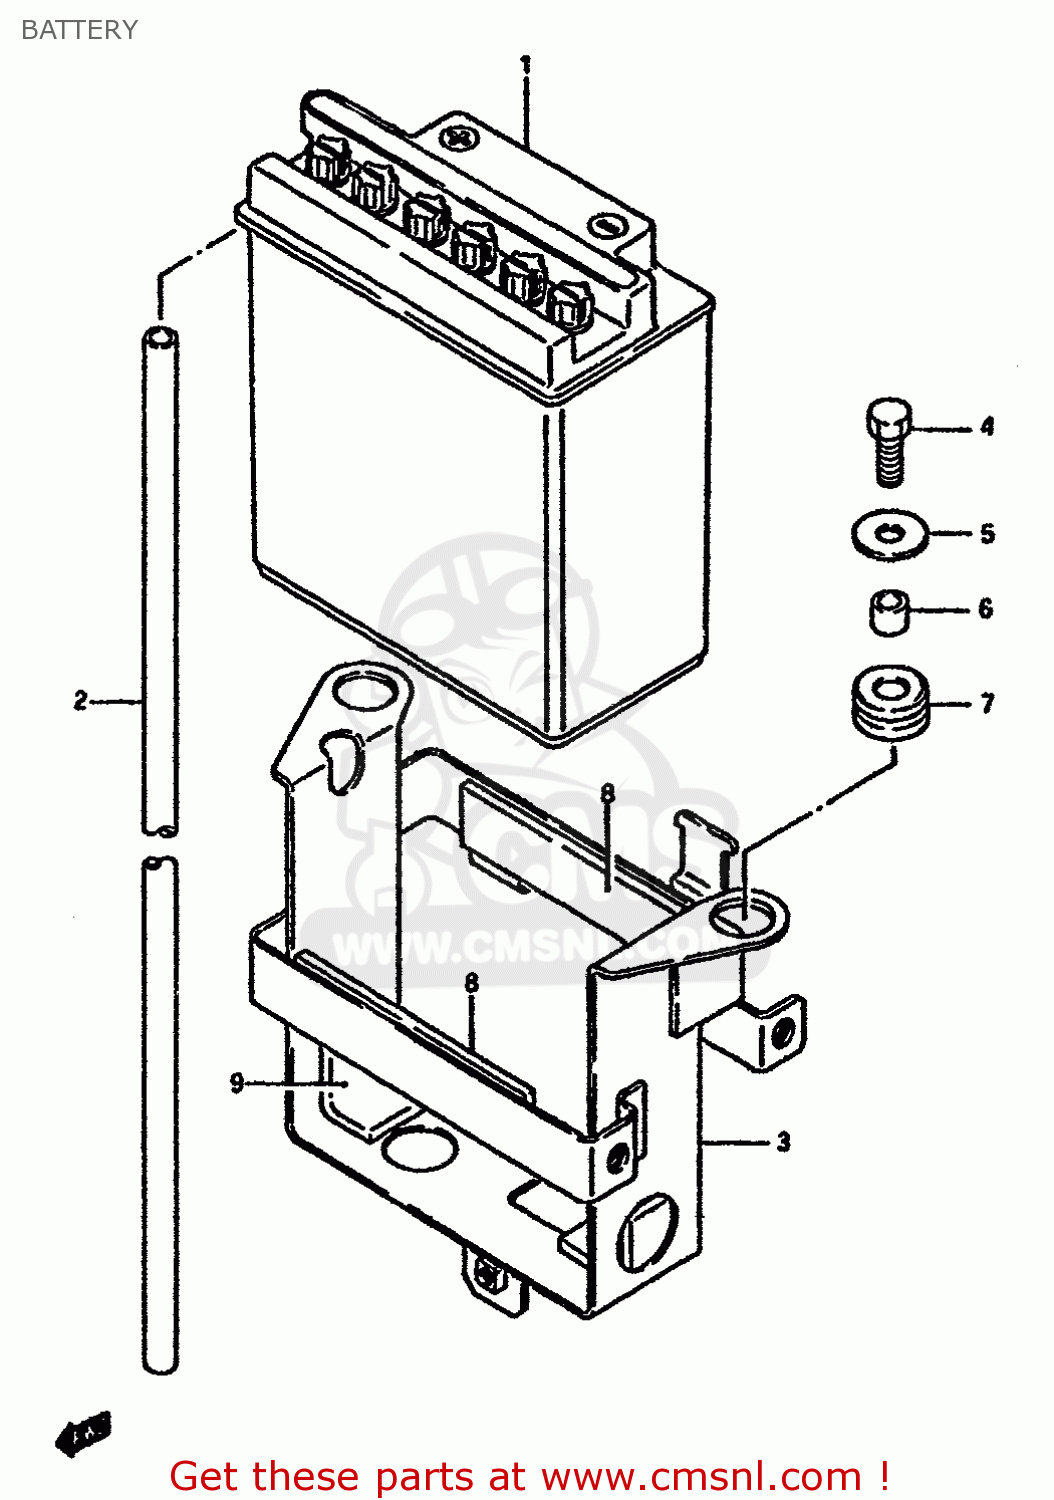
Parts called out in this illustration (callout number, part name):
1	BATTERY ASSEMBLY (12V)
2	HOSE,BATTERY EXHAUST
3	HOLDER,BATTERY
4	BOLT,M6X1X20
5	WASHER (6.5X20X1.2)
6	SPACER(6.1X9X7.5)
7	CUSHION
8	PROTECTOR,20X9
9	PROTECTOR(30X80X2)
